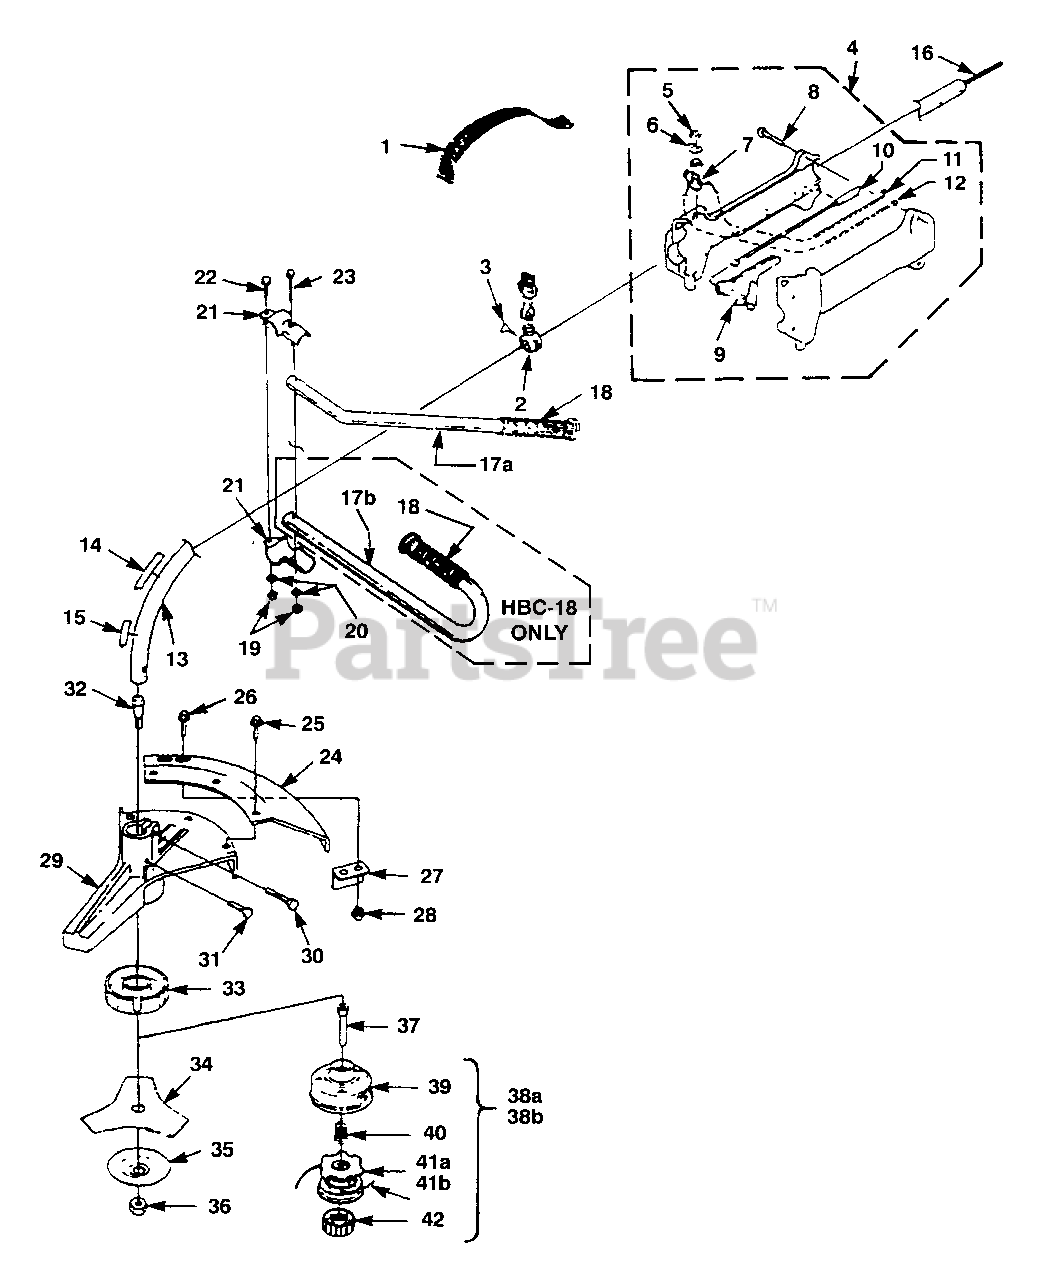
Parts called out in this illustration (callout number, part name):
1	HARNESS w/Connector
2	BRACKET - Hanger
3	SCREW - Thumb (10-24 X 1/2")
4	HANDLE GRIP ASSEMBLY
5	NUT - Toggle Switch - Hex Lock
6	PLATE - Indicating
7	SWITCH - Toggle
8	SCREW - Plastite (#8 X 3/4")
9	TRIGGER
10	CABLE - Throttle
11	LEAD - Electrical
12	LEAD - Ground
13	HOUSING - Drive Shaft (Black)
14	DECAL - Starting Instructions
15	DECAL - Warning
16	SHAFT - Flex
17A	HANDLE BAR
17B	HANDLE BAR ("J")
19	NUT (1/4-20)
20	WASHER (1/4")
21	CLAMP - Handle Bar
22	SCREW - Sems Hex Hd (1/4-20 X 1")
23	SCREW - Sems Hex Hd (1/4-20 X 1/2")
24	DEFLECTOR - Glass
25	SCREW - Mach Hex Hd (1/4-20 X 1/2")
26	SCREW - Mach Hex Hd (10-24 X 3/8")
27	BLADE - Cut-Off
28	NUT (10-24)
29	HOUSING - Lower Bearing
30	SCREW - Sems Hex Hd (1/4-20 X 1")
31	SCREW - Mach Hex Hd (10-24 X 3/8")
32	SHAFT - Spindle
33	WASHER - Flanged
34	BLADE - Tri-Arc (8")
35	WASHER - Cupped
36	NUT - Hex Locking (R.H.)
37	CONNECTOR - Drive
38A	STRINGHEAD - Complete
38B	STRINGHEAD - Complete
39	HOUSING & EYELET
40	SPRING - Compression
41A	SPOOL & STRING (.080" Line)
41B	SPOOL & STRING (.095" Line)
42	RETAINER - Spool (R.H. Thread)
